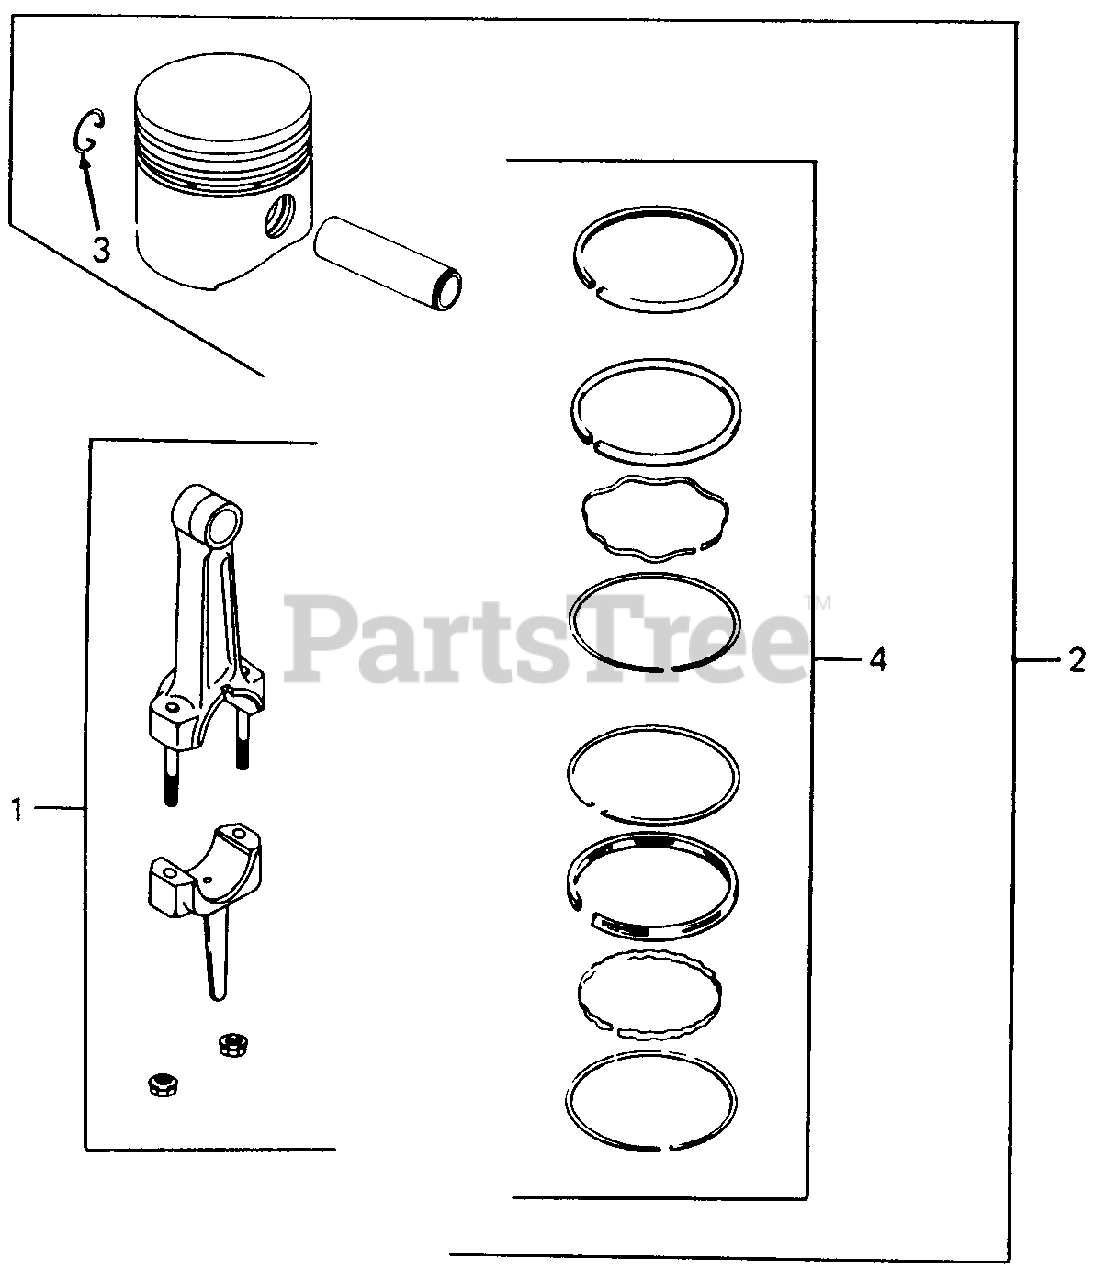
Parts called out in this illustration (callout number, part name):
1	Connecting Rod (Std)
2	Piston w/Ring Set (Std)
3	Retainer, Piston Pin
4	Ring Set (Std & .003)
